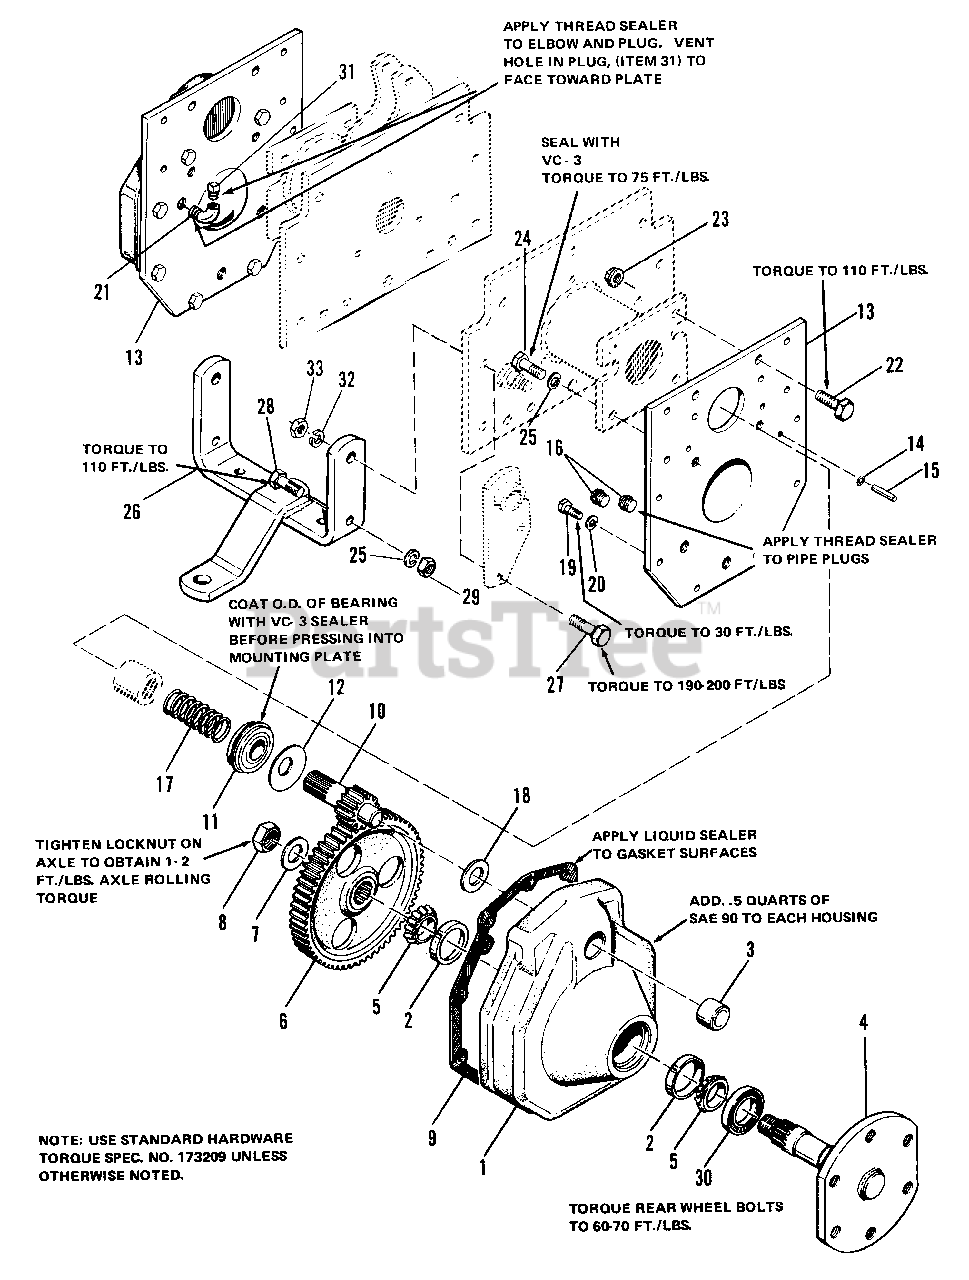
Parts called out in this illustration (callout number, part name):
1	HOUSING, Drop
2	BEARING, Cup
3	BEARING, Roller
4	AXLE ASSY, Rear
5	BEARING, Cone
6	GEAR, Bull
8	NUT, Hex, Lock, Jam, 1-14
10	PINION, Bull
11	BEARING, Axle
13	PLATE, Housing
15	PIN, Spring, 3/8-x 1
16	PIPE, Plug, 3/8
18	WASHER, Thrust
19	CAPSCREW, Hex, 3/8-16 x 1 Gr. 5
20	LOCKWASHER, 3/8
21	ELBOW, Street, 90ø, 1/4
22	CAPSCREW, Hex, 1/2-13 x 1-1/2 Gr. 8
23	NUT, Flange, 1/2-13
24	CAPSCREW, Hex, 1/2-13 x 1 Gr. 5
25	LOCKWASHER, 1/2
26	DRAWBAR ASSY
27	CAPSCREW, Hex, 5/8-11 x 2, Gr. 8
28	CAPSCREW, Hex, 1/2-13 x 1-1/2
29	NUT, Hex, 1/2-13
31	PLUG, Vent
32	LOCKWASHER, 5/8
33	NUT, Hex, 5/8-11
